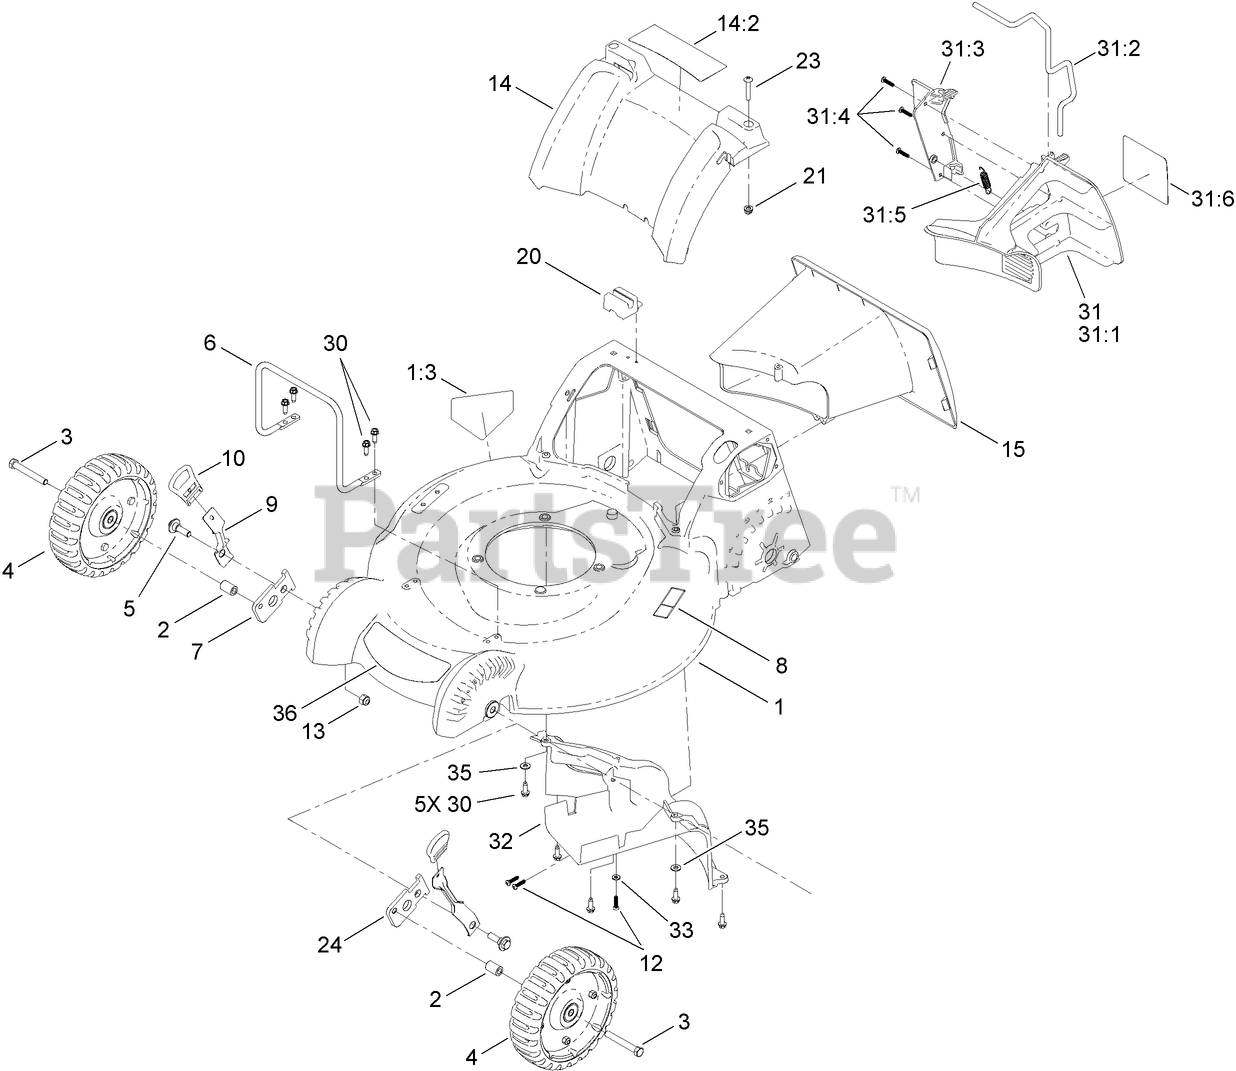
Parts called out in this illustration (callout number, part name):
1	HOUSING ASM
1:3	DECAL-DANGER
2	SPACER
3	SCREW-HH
4	8-INCH WHEEL ASM
5	SCREW-SHOULDER, HWH
6	GUARD-ENGINE
7	ARM-PIVOT, RH
8	DECAL-WARNING, BLOCK
9	ARM-SPRING, FRONT
10	KNOB-HOC
12	SCREW-PLASTITE
13	NUT-LOCK, NI
14	REAR COVER ASM
14:2	DECAL-WARNING
15	TUNNEL
20	MODULE-SWITCH
21	NUT-CLIP
23	SCREW-PTH
24	ARM-PIVOT, LH
30	SCREW-HWHTF
31	MULCH PLUG ASM
31:1	PLUG-MULCH, LH
31:2	LATCH-PLUG, MULCH
31:3	PLUG-MULCH, RH
31:4	SCREW-PLASTITE
31:5	SPRING-EXTENSION
31:6	DECAL-PLUG, MULCH
32	BAFFLE-REAR
33	WASHER-FLAT
35	WASHER-FLAT
36	DECAL-HOUSING, FRONT
